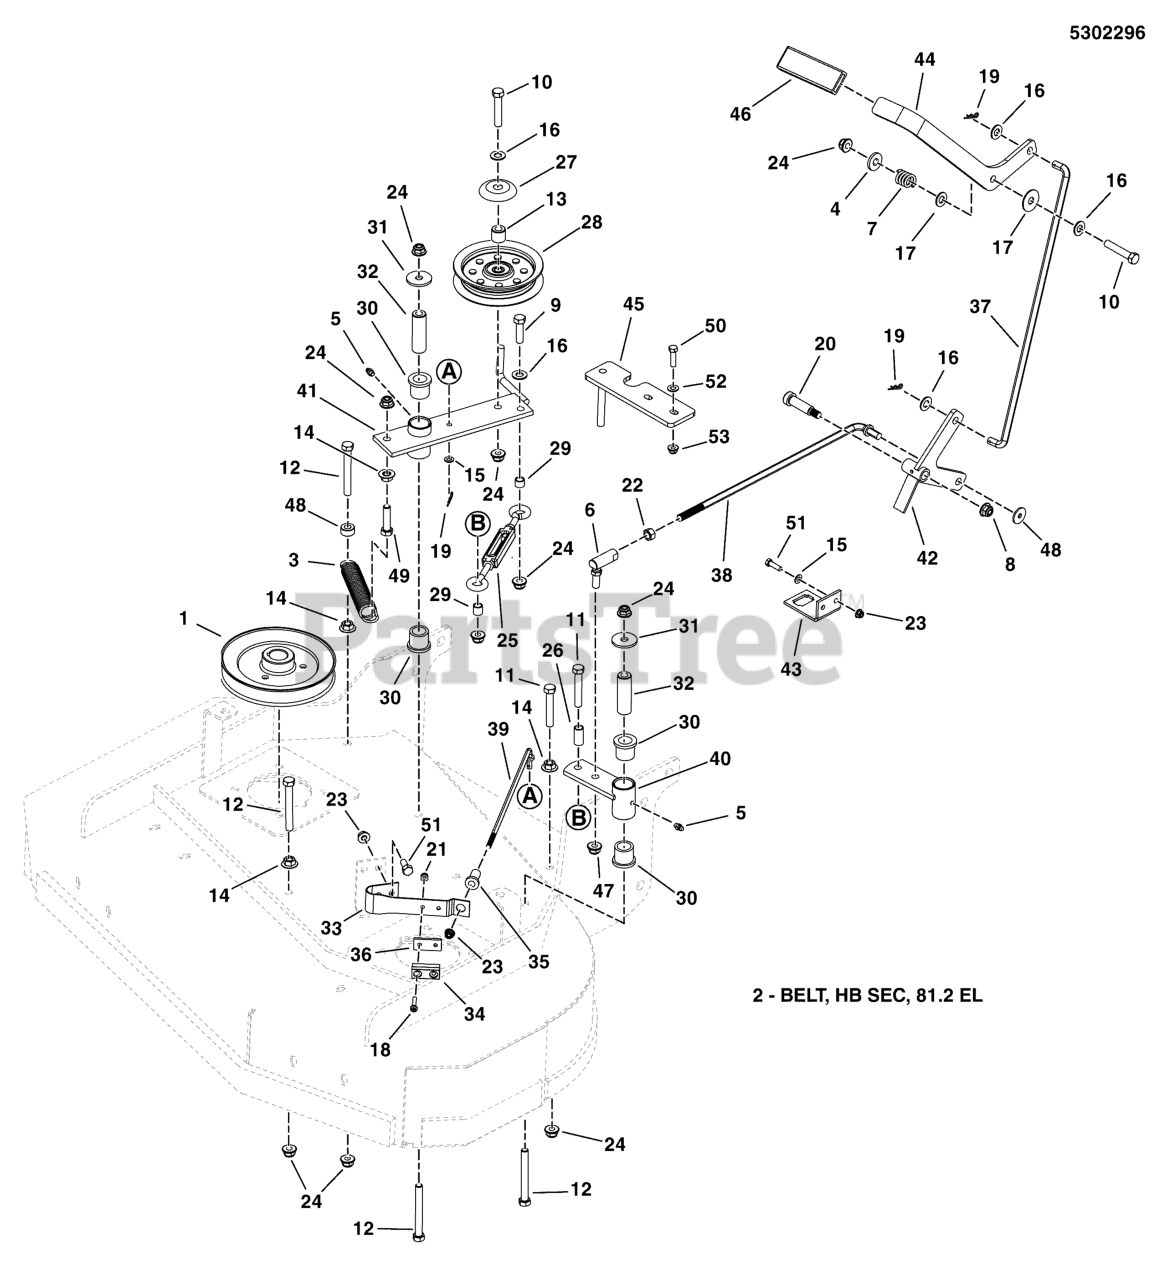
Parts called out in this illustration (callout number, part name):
1	PULLEY-6.122 OD. X .98 BORE
3	SPRING, EXTENSION, 1.00
4	WASHER-0.375(0.41IDX1.00ODX.13THK)BLK
5	GREASE FITTING, 1/4-28 STRAIGHT
6	BALL JOINT, 3/8-24 FEM, STUD
7	SPRING, COMPRESSION
8	NUT, 3/8-16 HEX SIDE LOCK
9	BOLT, 3/8-16 X 1-1/4" GD5 CZ
10	BOLT, 3/8-16 X 2, GD5, CZ
11	BOLT, 3/8-16 X 2-1/4" GD5 CZ
12	BOLT, 3/8-16 X 3-1/2" GD5 CZ
13	SPACER, .390 X 1.00 X .188, CZ
14	NUT, 3/8-16 HEX SERRATED FLANGE
15	WASHER, 1/4 SAE
16	WASHER, 3/8 SAE
17	WASHER-3/8 FENDER
18	SCREW, #10-24 X 1 RS, CZ
19	PIN, HAIR, .0585 X 1-1/8, 1/4 EYE, YZ
20	BOLT-3/8-16 x 1-1/2, 1/2 SHOULDER
21	NUT, #10-24 HEX NYLON LOCK
22	NUT, 3/8-24 HEX JAM
23	NUT, 1/4-20 HEX NYLOCK FLANGE
24	NUT, 3/8-16 HEX NYLOCK FLANGE
25	TURNBUCKLE ASSY
26	SPACER, .38 X .50 X 1.00
27	SHIELD, PULLEY BEARING
28	PULLEY-IDLER, 4.06OD, .375ID, .75W STL
29	SPACER, .38 X .50 X .38, CZ
30	BUSHING, FLANGED, 3/4 X 1 X 1
31	WASHER, .390 X 1.38 X .109, YZ
32	SPACER, .39 X .75 X 2.375, CZ
33	SPRING, PULLEY BRAKE
34	PAD, PULLEY BRAKE
35	BUSHING, .312 X .50 X 1.00, FLG
36	SPACER, BRAKE PAD, SW5
37	ROD, PTO, UPPER, SW5
38	ROD, PTO, LOWER, SW5
39	ROD, BRAKE CONTROL, DECK, SW5
40	WELD, BLADE ENGAGEMENT ARM - RED
41	WELD, IDLER ARM - RED
42	WELD, BLADE ENGAGEMENT PIVOT - RED
43	BRACKET, SWITCH MOUNT - RED
44	PLATE, BLADE ENGAGEMENT - RED
45	WELD, ADJUSTABLE BELT KEEP - RED
46	GRIP, FOAM, 1/4 X 1 X 4.1
47	NUT, 3/8-16 HEX NYLON LOCK
48	COLLAR, 3/8 SET
49	BOLT, 3/8-16 X 1-1/2" GD5 CZ
50	BOLT, 5/16-18 X 1 GD5
51	BOLT, 1/4-20 X 3/4 GD5
52	WASHER, 5/16" SAE
53	NUT, 5/16-18 HEX NYLOCK FLANGE
